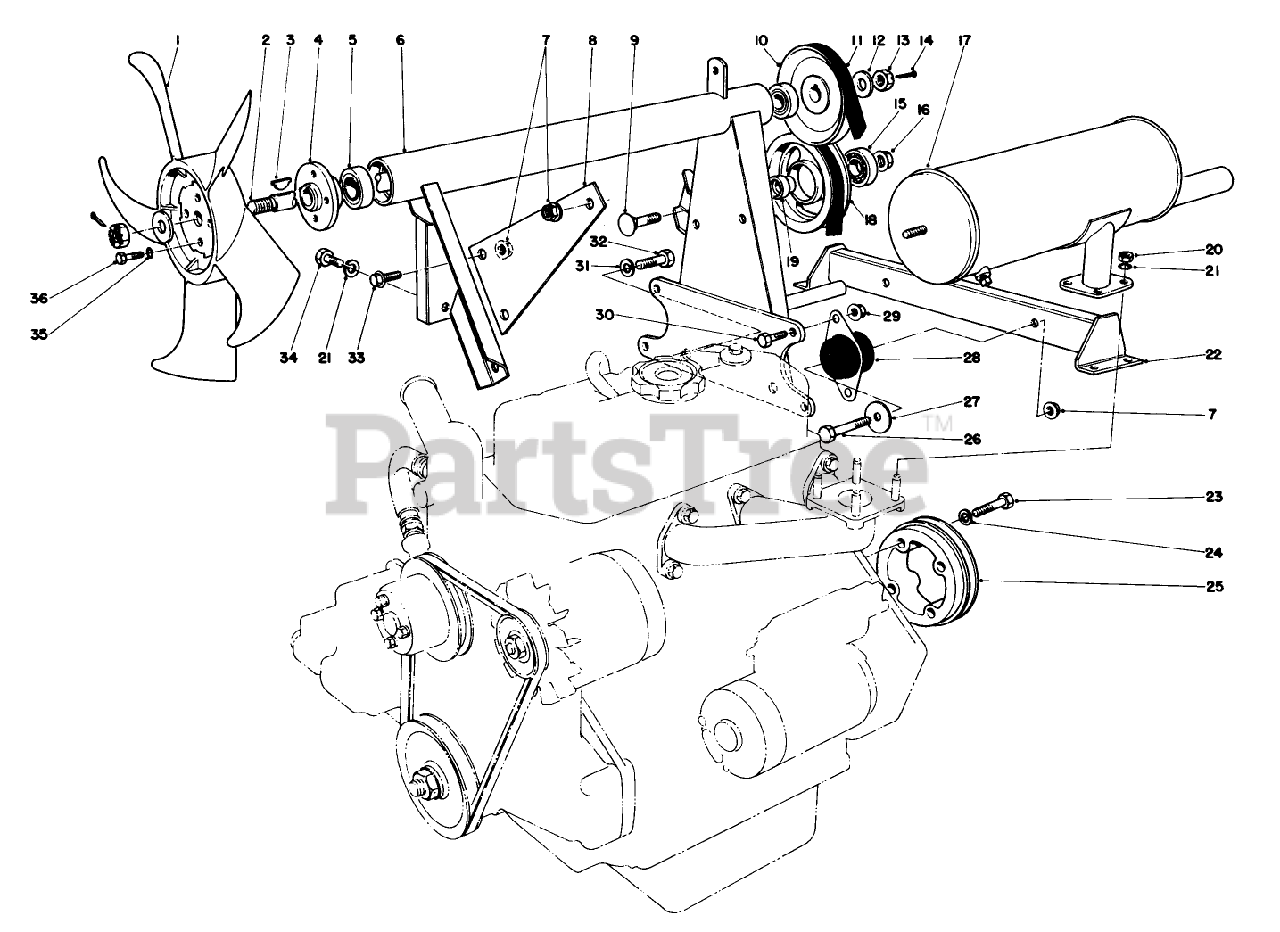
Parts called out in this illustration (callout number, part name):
1	Fan
2	SHAFT-FAN
3	KEY-WOODRUFF
4	HUB - FAN
5	BEARING-BALL
6	FAN MOUNT WA BO
7	NUT-HHF, WHIZ
8	Support Muffler
9	SCREW-CARR
10	Pulley
11	FAN BELT
12	WASHER
13	NUT-SHH
14	PIN-COTTER
15	Bearing
16	NUT-HF
17	MUFFLER
18	Idler Pulley (Incl. Ref. #15)
19	SPACER IDLER PULLEY
20	NUT-HEX
21	WASHER-LOCK, SPRING
22	Engine Mount
23	HEX HD CAPSCREW
24	WASHER-LOCK, SPRING
25	Pulley Flywheel
26	SCREW-HH
27	WASHER-TOP THRUST
28	Engine Mount Rubber
29	NUT-HF
30	SCREW-HHF
31	WASHER-LOCK, SPRING
32	SCREW-HH
33	SCREW-HHF
34	BOLT
35	WASHER-LOCK
36	SCREW-HH
